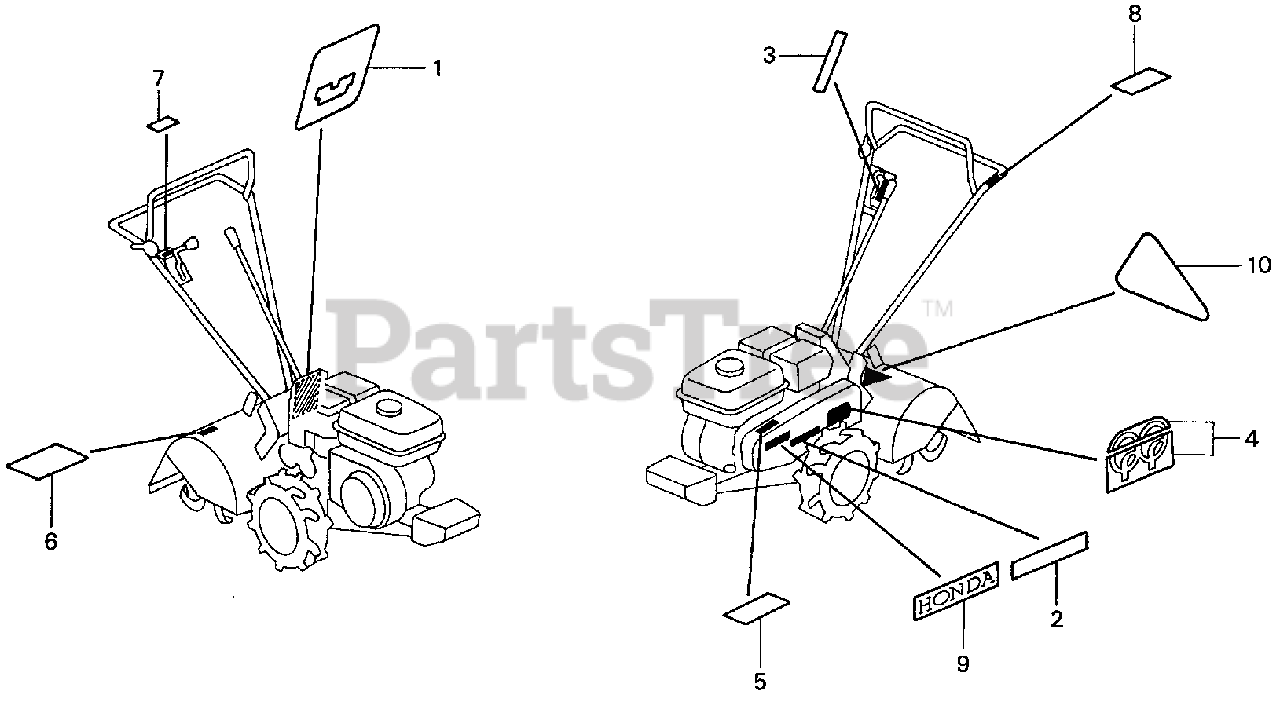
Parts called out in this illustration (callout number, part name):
1	MARK, CHANGE
2	MARK, L. STRIPE (FR750)
3	MARK, DIFFERENTIAL LOCK (E)
4	MARK, SIDE EMBLEM
5	LABEL, BELT WARNING
6	LABEL, TINE DANGER
7	MARK, ENGINE SWITCH INDICATION
8	MARK, MAIN CLUTCH INDICATION
9	EMBLEM (13) (HONDA)
10	MARK, ROTARY
